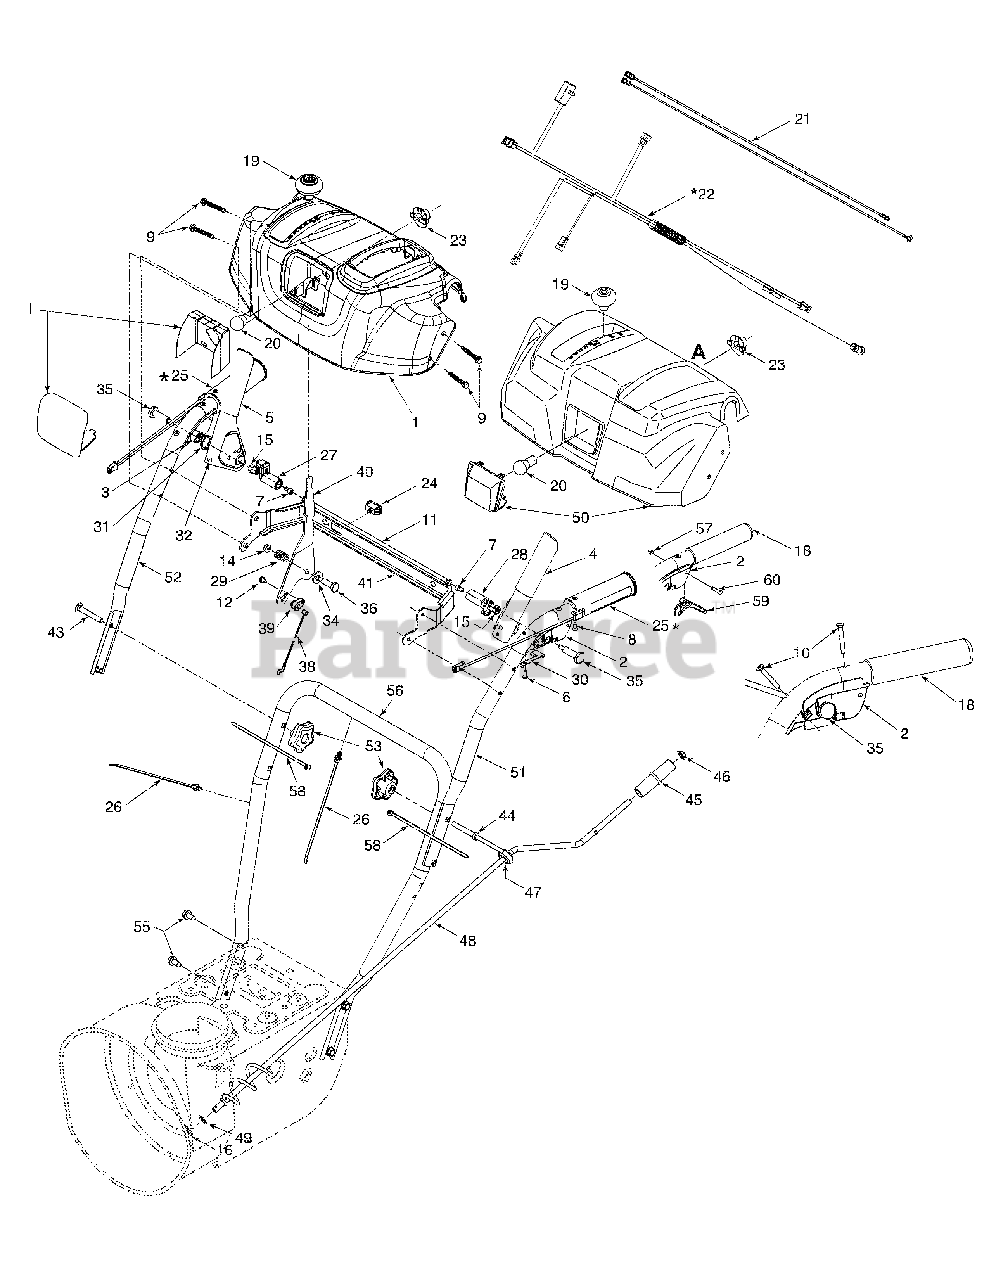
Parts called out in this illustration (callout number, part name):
1	Handle Panel Ass’y - Yellow
1	Handle Panel Ass’y - Black
1	Handle Panel Ass’y-Black w/Chute Control
2	LH Clutch Lock Handle Ass’y
3	RH Clutch Lock Handle Ass’y
4	Engagement Handle Assembly LH
5	Engagement Handle Assembly RH
6	Screw #8-16 x .50
7	Screw 1/4-20 x .375
8	Oval HD C-Sunk Scr #10 x 5/8
9	Hex TT-Tap Scr 1/4-20 x 1.625
10	Oval C-Sunk Hd Screw 10-24 x 1.375
11	Pivot Rod
12	Screw #10-16 x .50
14	Hex L-Flanged Nut 1/4-20 Gr. F Nylon
15	Hex Shoulder Nut 1/4-20
16	Int. Cotter Pin .072 x 1.13" Lg.
19	Shift Knob
19	Shift Knob - Yellow
20	Lamp #1295 (w/heated grips)
20	Lamp
21	Wire Harness
22	Heated Grip Wire Harness
23	Socket
24	Switch
25	Heated Grip
26	Cable Tie 19 x 8.39" (w/plug)
26	Cable Tie (w/heated grips)
27	Lock Plate
28	Clutch Lock Cam
29	Compression Spring .38 ID x .88 Lg
30	Spring: Clutch Lock
31	Torsion Spring .8156 x .3038
32	Rubber Bumper
34	Flat Washer .38 ID x .87 OD x .09
35	Shoulder Screw 1/4-20 x 1.345
36	Shoulder Screw .374 Dia. x 1.05 Lg.
38	Selector Speed Cable
39	Cable Barrel Holder
43	Carriage Bolt 5/16-18 x 2.25
44	Chute Crank Eye Bolt Special
45	Knob 1.0 x 3.2
46	Push Nut 3/8" Rod
47	Grommet
49	Flat Washer .406" I.D. x .75" O.D.
50	Handle Panel Ass’y - Troy-Bilt
53	Handle Knob Assembly
55	Hex Wash HD Lo Tap Scr 5/16 x .75
57	E Ring
58	Cable Tie
59	Steering Control
60	Pin 3/16
